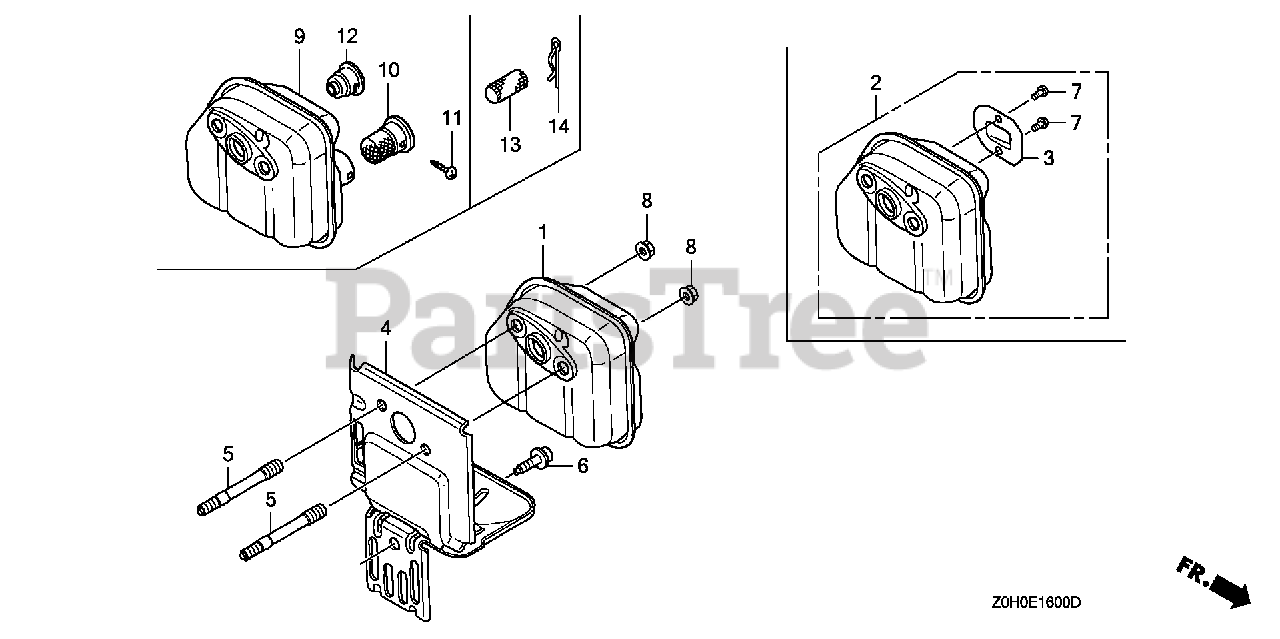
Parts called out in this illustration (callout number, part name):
2	MUFFLER
3	ARRESTER, SPARK
4	GUIDE, AIR EX.
5	BOLT, STUD (5X52)
6	BOLT, SOCKET (5X10) (CT)
7	SCREW, TAPPING (4X6)
8	NUT, SELF-LOCK (5MM)
